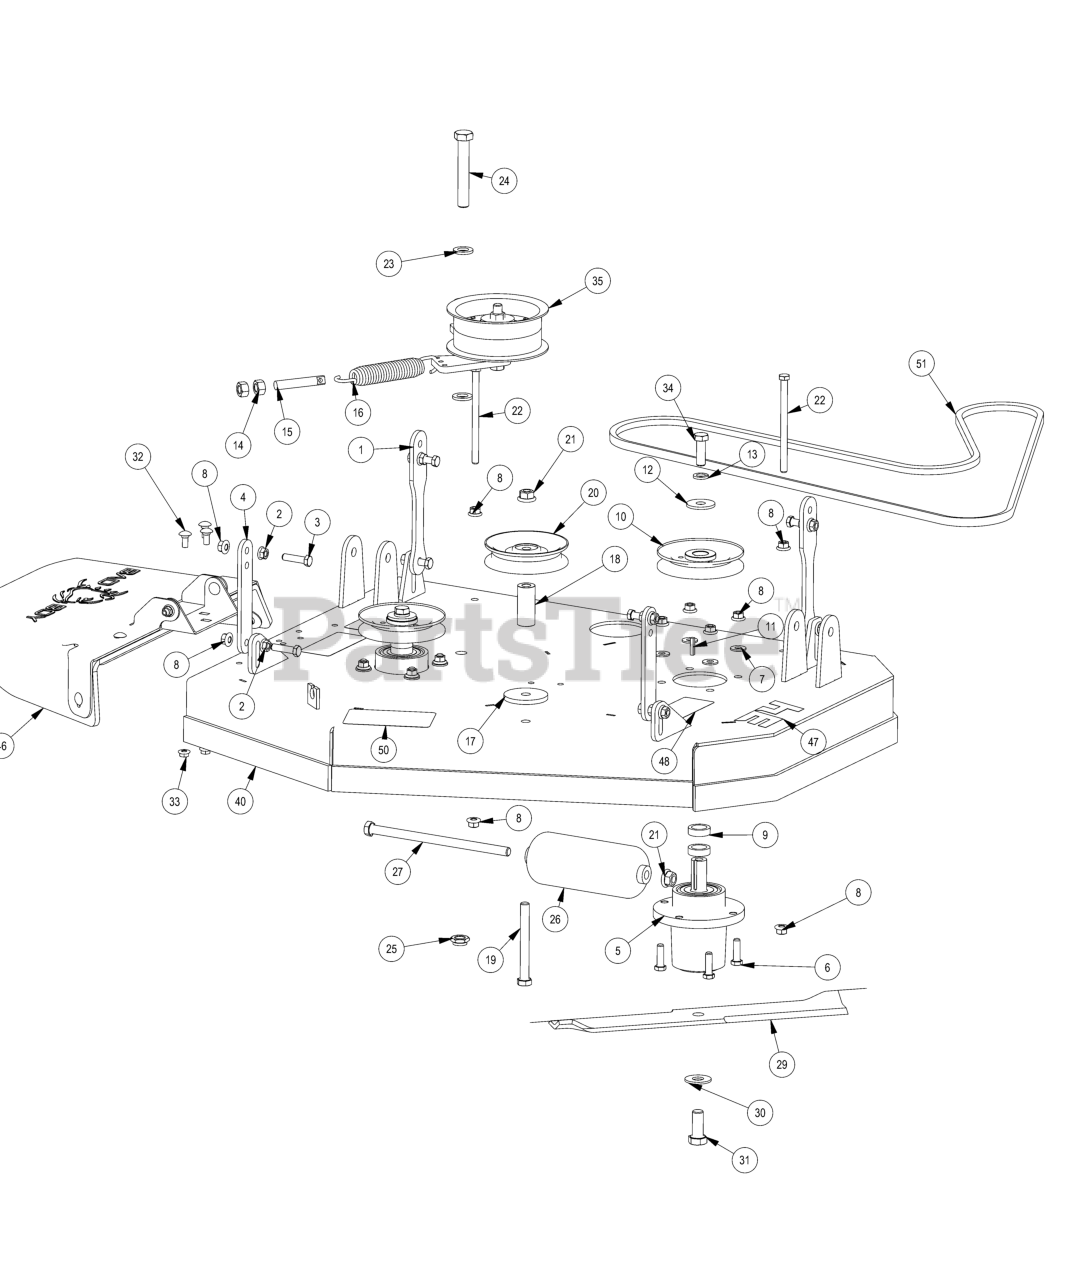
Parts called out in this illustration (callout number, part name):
1	2019 Stand-On Rear Deck Hanger
2	3/8-16 HEX SERRATED FLANGE NUT HARD/ZINC
3	3/8-16 X 1-1/2 HEX CAP SCREW (GR.5) ZINC
4	2019 Revolt Front Deck Hanger
5	36'' Revolt Spindle Assembly
6	3/8-16 X 1-1/4 HEX CAP SCREW (GR.5) ZINC
7	5/16 USS FLAT WASHER (7/8 OD) ZINC
8	3/8-16 NYLON INSERT FLANGE LOCKNUT (GR.F) ZINC
9	36 Deck Spindle Spacer
10	MZ Deck Pulley
11	3/16 X 1 SQ MACHINERY KEY 1018 STL ZINC
12	1/2 BELLEVILLE WASHER (1-5/8 OD X .140 THK) ZINC
13	1/2 SPLIT LOCKWASHER (GR.8) ZINC/YELLOW
14	1/2-13 HEX NUT ZINC
15	All Thread
16	Deck Idler Spring
17	MZ Deck Idler Spacer
18	2019 Revolt Stationary Idle Spacer
19	1/2-13 X 4-1/2 HEX CAP SCREW (GR.5) ZINC
20	5 V Idler Pulley 1/2" Bore
21	1/2-13 NYLON INSERT FLANGE LOCKNUT ZINC
22	3/8-16 X 5-1/2 HEX CAP SCREW (GR.5) ZINC
23	.635 ID X 1.120 OD X .140 THICK FLAT WASHER NYLON
24	5/8-11 X 4 HEX CAP SCREW (GR.8) ZINC YELLOW
25	5/8-11 NYLON INSERT JAM LOCKNUT ZINC
26	3in deck roller
27	1/2-13 X 9 HEX CAP SCREW (GR.5) ZINC
29	34'' DeckBlade
30	5/8'' Flat Washer
31	5/8-18 X 1-1/2 HEX CAP SCREW (GR.8) ZINC YELLOW
32	5/16-18 x 3/4 Carriage Bolt
33	5/16-18 HEX SERRATED FLANGE NUT HARD/ZINC
34	1/2-20 X 1-1/2 HEX CAP SCREW (GR.5) ZINC
35	5 3/4" Deck Idler Pulley
36	2020 36 Deck Idler Arm Weldment
37	1/4-28 Grease Fitting
38	1/2-13 X 3-1/2 HEX CAP SCREW (GR.5) ZINC
40	2024 34 Stand On Deck Weldment
46	MZ Discharge Chute Assembly
47	34" Deck Decal
48	Danger Decal-Spindle/Discharge
49	Deck Impact Patent Decal 9591803
50	36" Revolt Deck Belt Route Decal
51	34'' deck belt 94.25''
